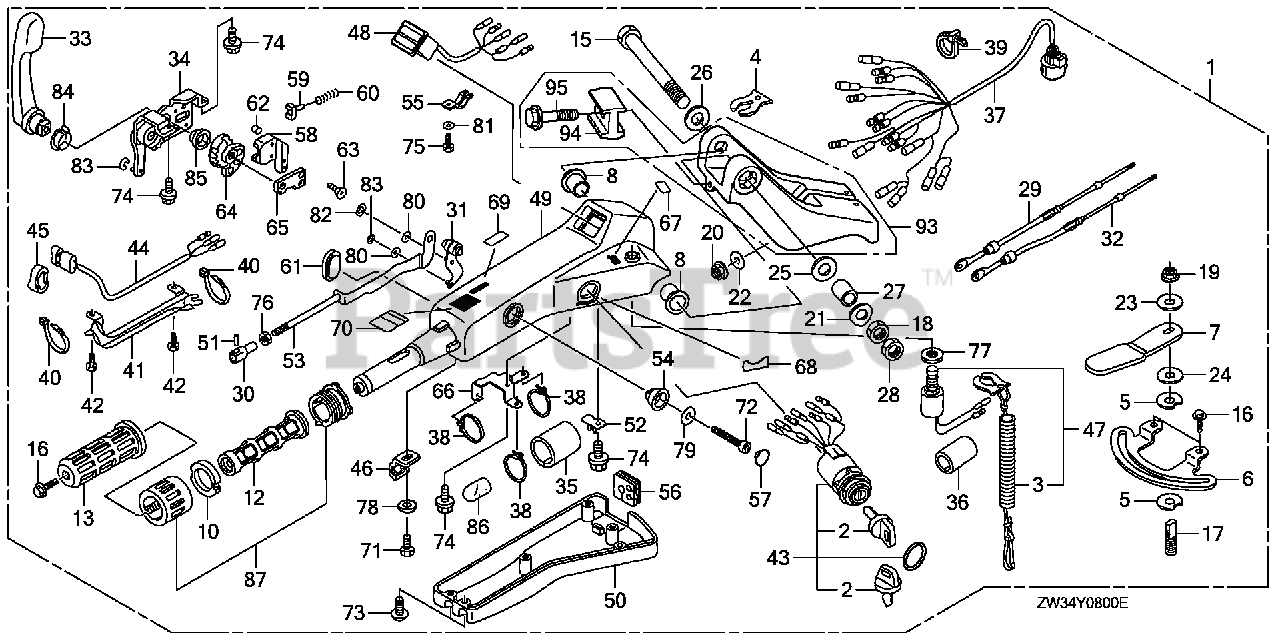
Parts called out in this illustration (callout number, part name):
1	HANDLEBAR KIT *NH282MU* (OYSTER SILVER METALLIC-U)
2	KEY ASSY., COMBINATION SWITCH (35100-ZV5-003 ONLY) DUAL QTY = (4) (SINGLE)
3	WIRE, EMERGENCY (SINGLE) (DUAL)
4	CLIP, EMERGENCY LOCK
5	BLOCK, FRICTION
6	PLATE, FRICTION
7	LEVER, FRICTION
8	BUSH, HANDLEBAR
9	GRIP ASSY., THROTTLE FRICTION
10	PAD, THROTTLE FRICTION
11	GRIP ASSY., THROTTLE FRICTION
11	BLOCK, THROTTLE FRICTION
12	PIPE, GRIP
13	RUBBER, GRIP
14	BRACKET, STEERING *NH282MU* (OYSTER SILVER METALLIC-U)
15	BOLT, HEX. (12X80)
16	BOLT, FLANGE (6X12) Use from Frame SN 1005249.
17	BOLT, STUD (8X26)
18	NUT, HEX. (12MM)
19	NUT, SELF-LOCK (8MM)
20	NUT, SELF-LOCK (10MM)
21	WASHER, WAVE (14MM)
22	WASHER (10MM)
23	WASHER (8MM)
24	WASHER, NYLON (8MM)
25	WASHER, PLAIN (12MM)
26	WASHER, PLAIN (12MM)
27	COLLAR, DISTANCE (12.2X23X16)
28	NUT, HEX. (12MM)
29	CABLE, THROTTLE
30	PIVOT, THROTTLE CABLE
31	ARM, THROTTLE
32	CABLE, SHIFT
33	LEVER, SHIFT
34	FRAME ASSY., SHIFT
35	TUBE (38.1X40)
36	TUBE (19X40)
37	CABLE ASSY., LONG HANDLE (A)
38	BAND (CONVEX CV-150)
39	BAND (CONVEX CV-200)
40	BAND (CONVEX)
41	COVER, WIRE
42	SCREW
43	SWITCH ASSY., COMBINATION
44	SWITCH ASSY., POWER TILT
45	GROMMET
46	HOLDER, SWITCH
47	SWITCH ASSY., EMERGENCY STOP
48	LAMP ASSY., INDICATION (2-LED) DUAL QTY = (2) (SINGLE)
49	HOUSING *NH282MU* (OYSTER SILVER METALLIC-U)
50	COVER, HANDLEBAR (LOWER)
51	PIN, THROTTLE CABLE
52	BRACKET, CABLE
53	PLATE ASSY., LOCK
54	STOPPER
55	PLATE, GUIDE
56	GROMMET
57	CAP
58	GUIDE, SPRING
59	ACTUATOR
60	SPRING, COIL
62	ROLLER
63	SCREW (M5X14)
64	GEAR, SHIFT
65	PLATE, BALL GUIDE
66	BRACKET
67	MARK, EMERGENCY SWITCH INDICATION
68	MARK, STARTER (ENGLISH)
69	MARK, CHANGE (JAPANESE/ENGLISH)
70	MARK, THROTTLE (ENGLISH)
71	BOLT (M5X8)
72	BOLT (M8X50)
73	BOLT (M5X12)
74	BOLT (M6X12)
75	BOLT (M5X12)
76	NUT, HEX. (5MM)
77	NUT, HEX. (16MM) DUAL QTY = (2) (SINGLE)
78	WASHER (5MM)
79	WASHER (8MM)
80	WASHER (10MM)
81	WASHER (5MM)
82	E-RING
83	E-RING
84	BEARING
85	BEARING
86	TUBE, CORD (30MM)
87	GRIP ASSY., THROTTLE FRICTION
93	BRACKET KIT, STEERING *NH282MU* (OYSTER SILVER METALLIC-U)
94	BLOCK, HEIGHT ADJUSTER
95	BOLT, FLANGE (8X28)
